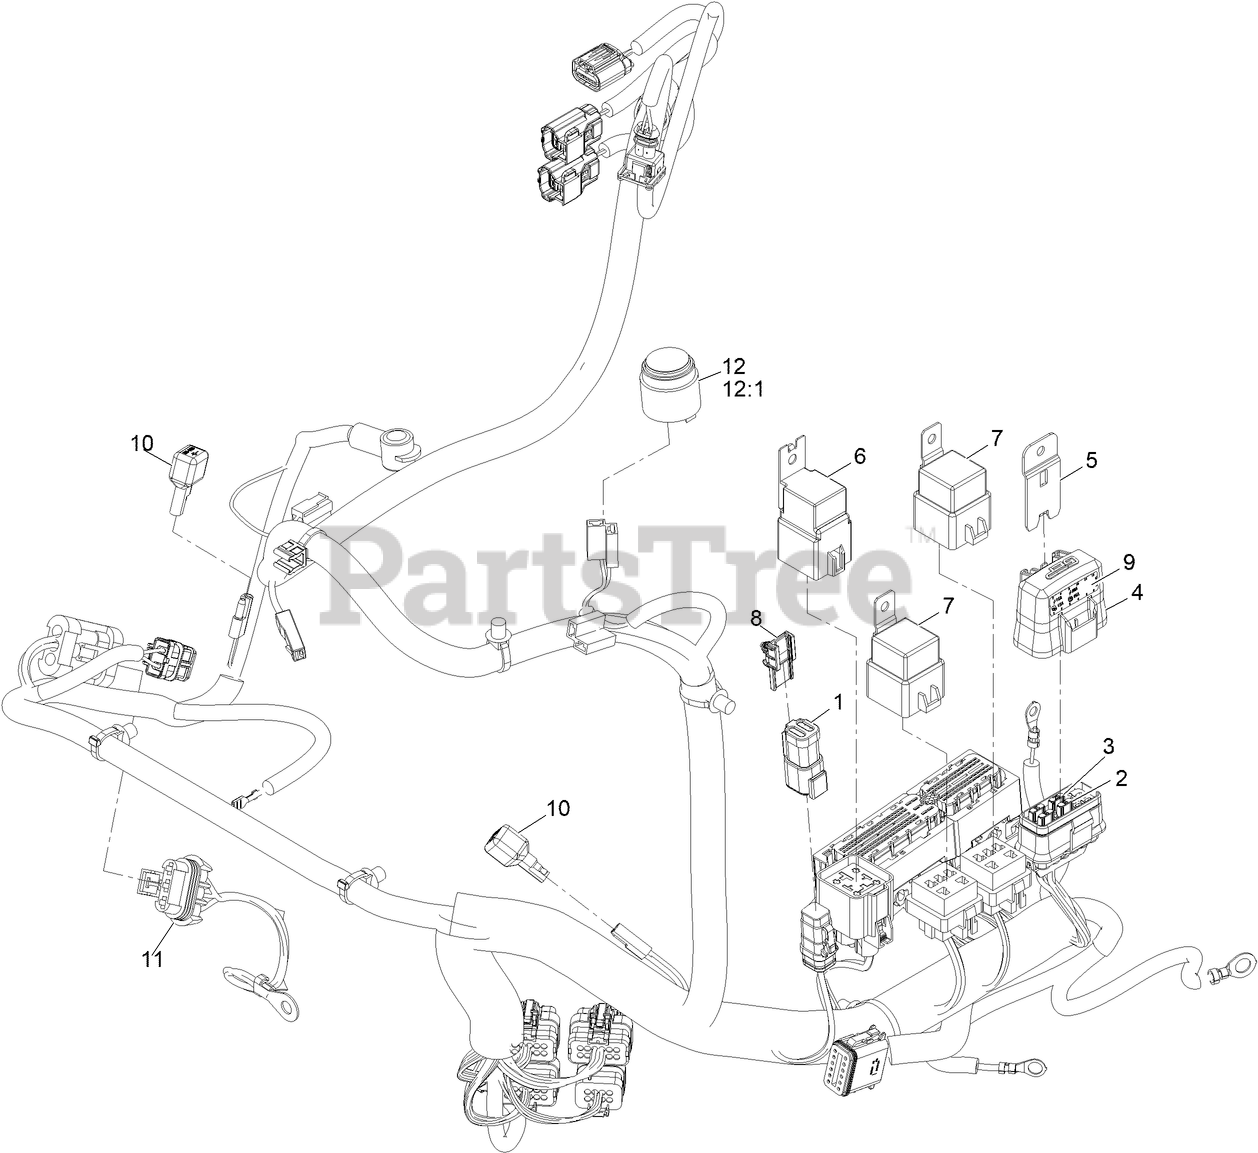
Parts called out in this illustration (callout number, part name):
1	CONNECTOR (6M)
2	FUSE-MINI BLADE, 15 AMP
3	FUSE-MINI BLADE, 25 AMP
4	COVER-BLOCK, FUSE
5	CLIP-MOUNTING
6	RELAY-70A
7	RELAY-MINI
8	CLIP-CONNECTOR
9	DECAL-FUSE
11	HARNESS-WIRE, FUSIBLE LINK
12	AUDIO ALARM ASM
12:1	NUT-PLASTIC, KNURLED
